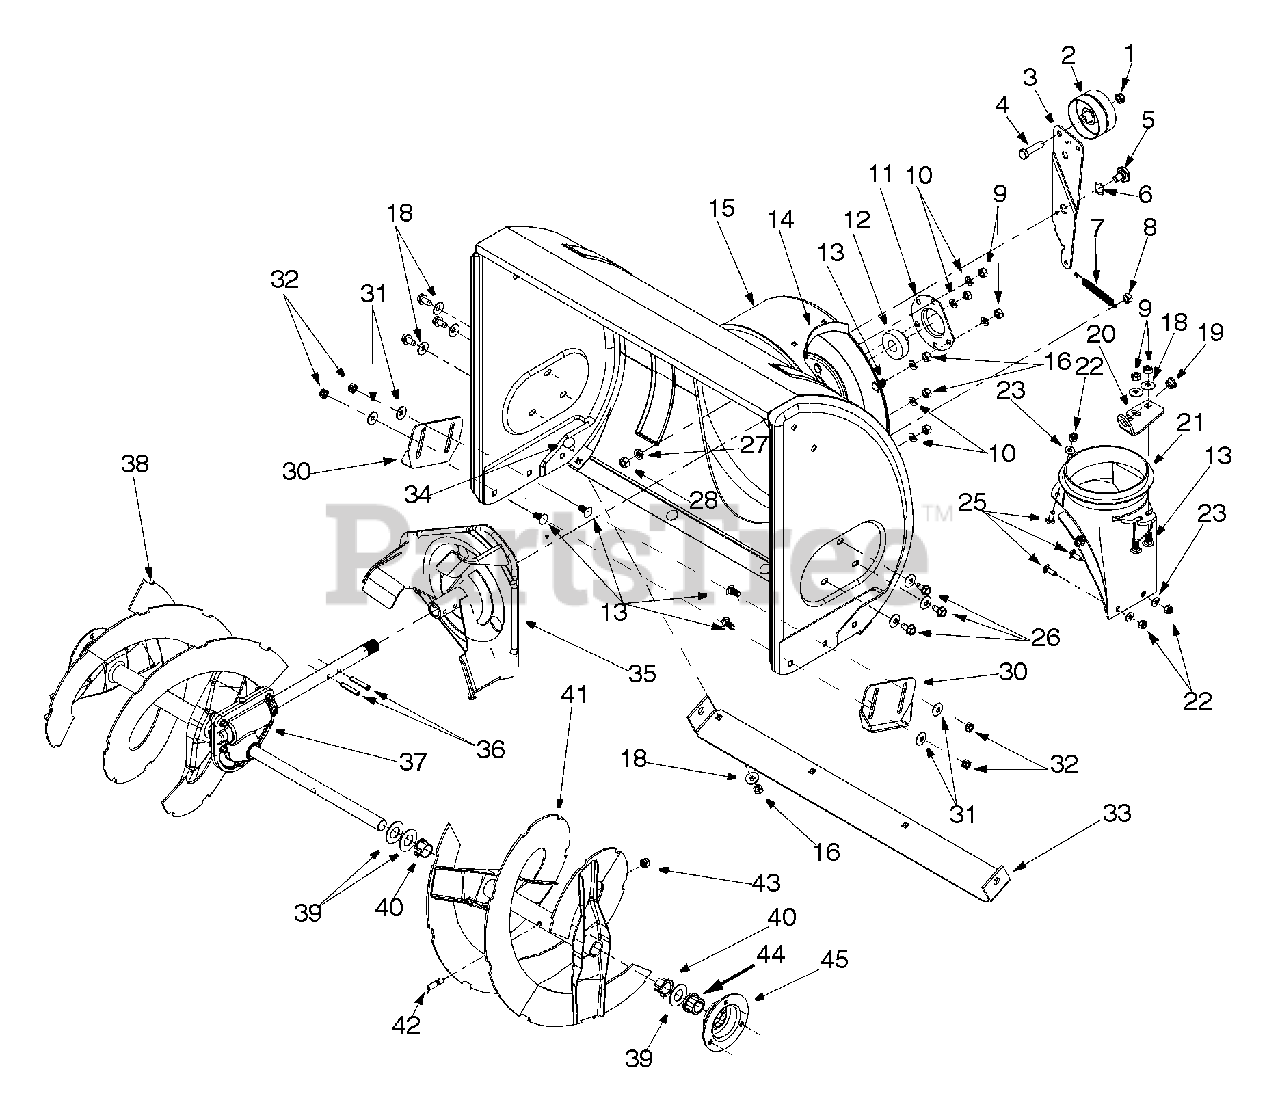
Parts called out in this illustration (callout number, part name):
1	Lock Jam Nut 3/8-24
2	Flat Idler
4	Hex Cap Screw 3/8-24 x 1.50
5	Shoulder Screw
6	Wave Washer
7	Extension Spring
8	Hex Nut 5/16-18
9	Hex Nut 5/16-18
10	Lock Washer 5/16
11	Housing
12	Ball Bearing
13	Carriage Bolt 5/16-18 x .75
18	Bell Washer
19	Bushing
21	Chute Adapter
22	Hex Lock Nut 1/4-20
23	Flat Washer
25	Carriage Screw 1/4-20 x .75
26	Hex Washer TT Screw 5/16-18
27	Lock Washer 3/8
28	Hex Nut 3/8-16
31	Bell Washer
32	Hex Nut 5/16-18
34	Carriage Bolt 5/16-18 x .62
37	24" Gear Assembly
39	Flat Washer
40	Flange Bushing
42	Shear Bolt 5/16-18 x 1.5
43	Lock Nut 5/16-18
44	Hex Flange Bearing
